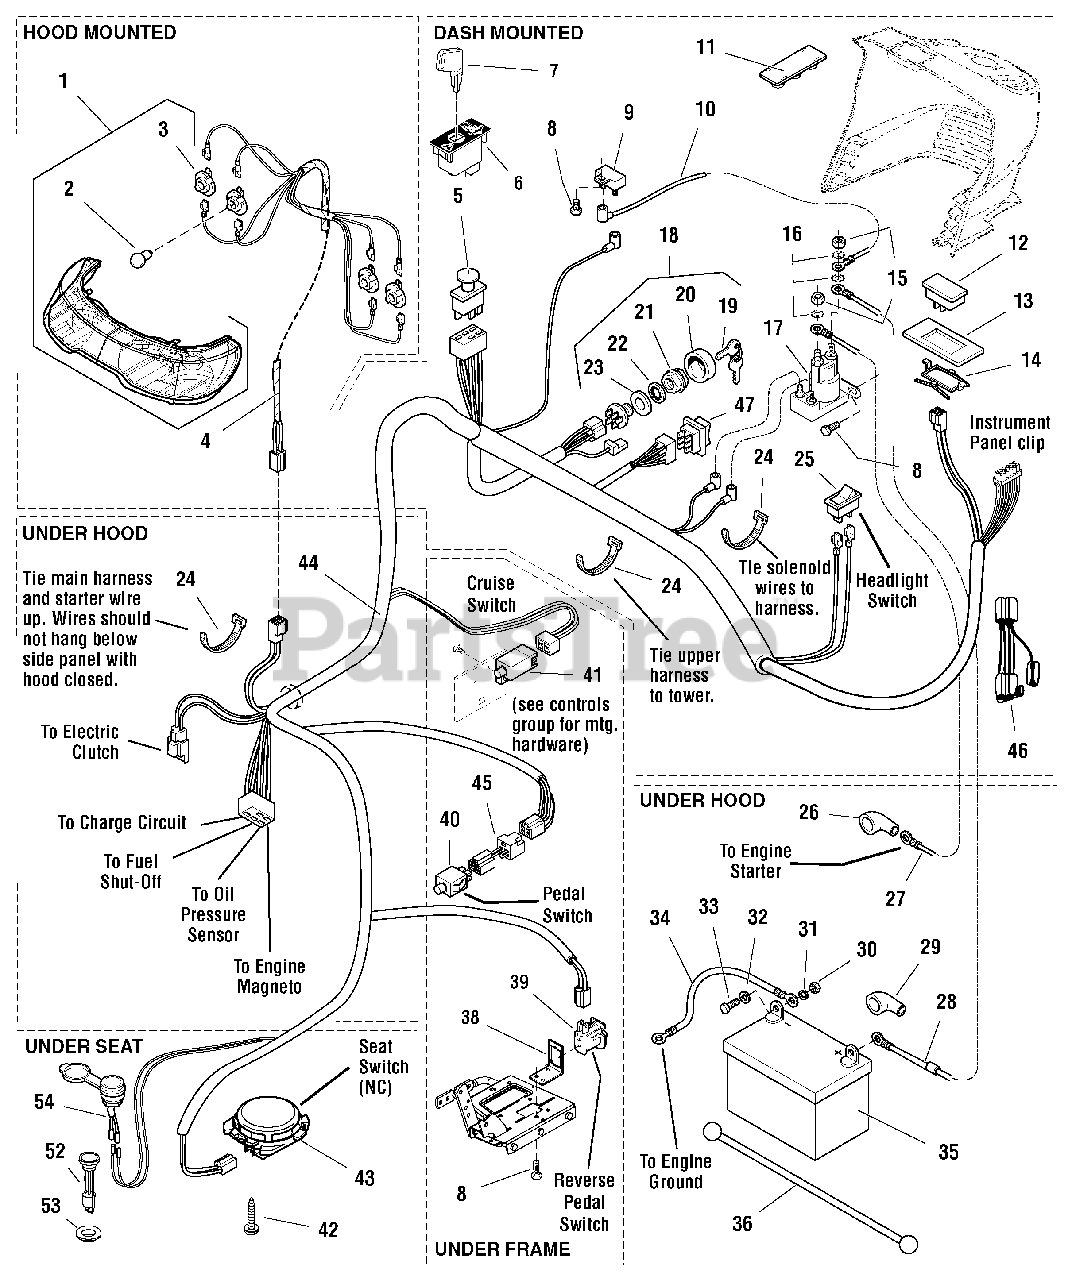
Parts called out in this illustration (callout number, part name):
1	HEADLIGHT ASSEMBLY, 4 Bulb, (Includes Ref. Nos. 2 & 3)
2	BULB, Headlight, 12.8V
3	SOCKET ASSEMBLY, Headlight, Sealed
4	HARNESS, Headlight
5	SWITCH, PTO Push/Pull Symbols
6	SWITCH, RMO Module Only
7	KEY, RMO Module, Plastic
8	CAPSCREW, Hex Washer Head Taptite, 1/4-20 x 1/2, Black
9	BREAKER, Circuit, 12 Volt 20 Amps
10	WIRE, 12GA 5-15/16 Long, Red
11	PLUG, Hole, Square
12	HOUR METER
13	PLUG, Dash
14	CLIP, Hour Meter (Service Only)
15	NUT, Hex, 5/16-24
16	LOCKWASHER, External Tooth, 5/16
17	SOLENOID
18	SWITCH ASSEMBLY, Ignition, 6 Pin, (Includes Ref. Nos. 17, 18, 19, 20 & 21)
19	KEYS, Set of 2
20	COVER, For Ignition Switch, Plastic
21	NUT, Hex Flange, 5/8-32, Ignition Switch
22	LOCKWASHER, Internal Tooth, 5/8, Thin
23	WASHER, Shim
24	TIE, Strap, 7-5/16 Long
25	SWITCH, Headlights , 2 Terminal
26	BOOT, Insulator Cable Terminal, 1-15/16 Long, Red
27	CABLE, #6 x 25" Long, Ring Terminals
28	CABLE, #6 x 8" Long, Ring Terminals
29	BOOT, Insulator Battery Terminal
30	NUT, Hex, 1/4-20
31	LOCKWASHER, 1/4
32	WASHER, 1/4
33	CAPSCREW, Hex Head, 1/4-20 x 3/4
34	CABLE, #6 x 26 Long, Ring Terminal
35	BATTERY, 12 Volt
36	STRAP, Battery, 14 Long, Rubber
37	CAPSCREW, Hex Head Taptite, 1/4-20 x 3/8
38	BRACKET, Switch Mount
39	SWITCH, Reverse Pedal
40	SWITCH, Push Button, Foot Pedal
41	SWITCH, Cruise Control, Grey, NO
42	CAPSCREW, Hex Washer Head Plastite, 1/4 x 1/2
43	SWITCH, Seat, Grey, NC
44	HARNESS, Wiring
45	WIRING ASSEMBLY, All Conditions Shutdown
46	HARNESS, Jumper Wire
47	SWITCH, Electric Lift Rocky
52	GAUGE, Fuel
53	GROMMET
54	OUTLET. 12V
